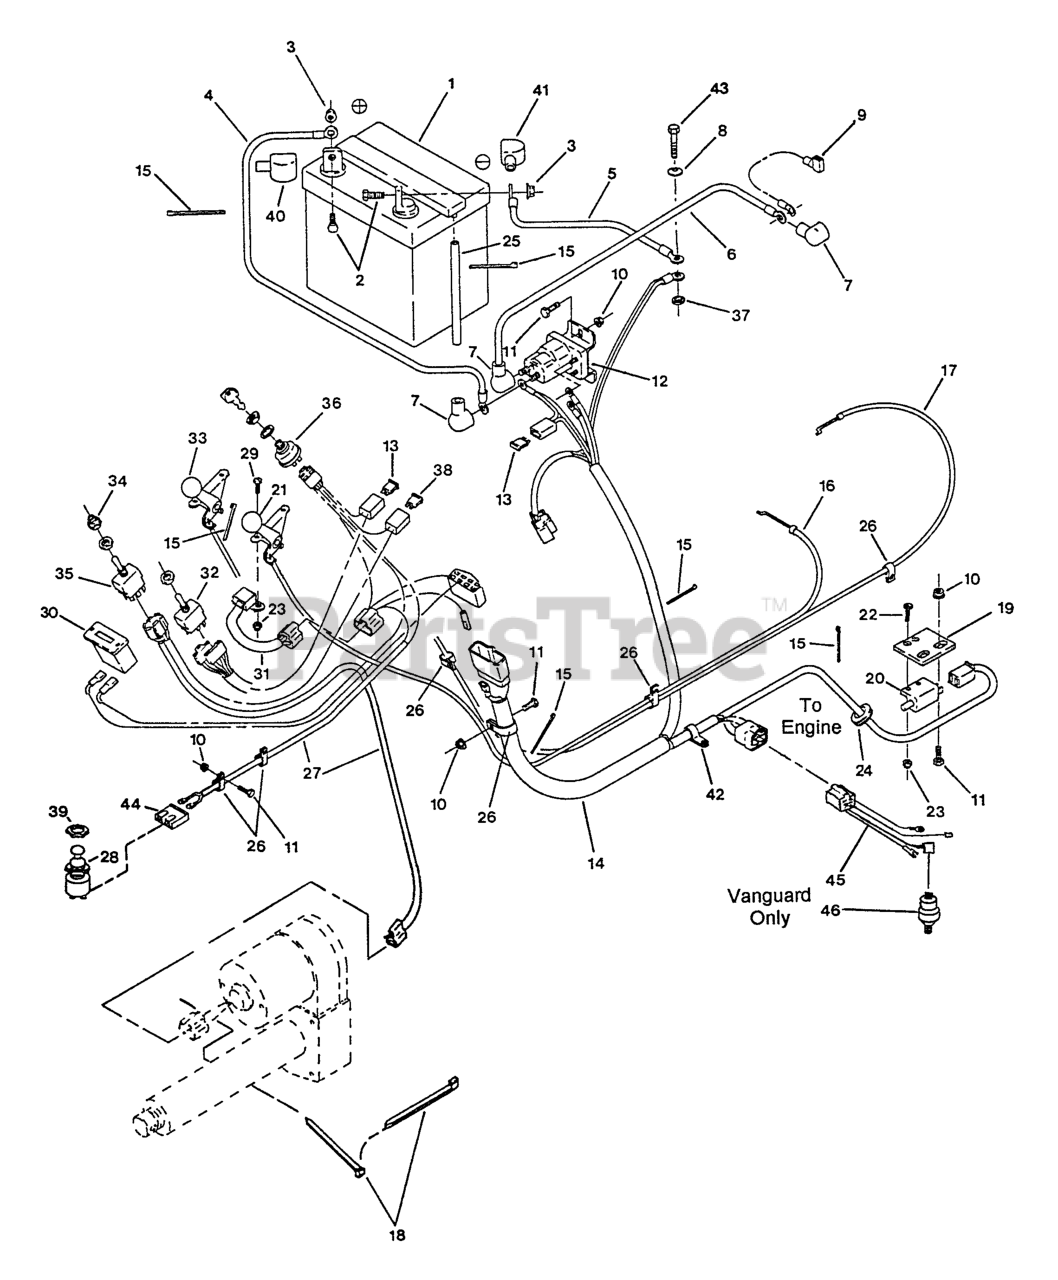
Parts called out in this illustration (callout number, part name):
1	Battery, 12 Volt
5	WIRE-GROUND
6	WIRE,BATTERY POSITIVE
7	INSULATOR-SOLENOID
8	WASHER-SPRING
13	FUSE-BLADE TYPE, 20 AMP
15	TIE-CABLE
18	TIE-PLASTIC
19	BRACKET,SAFETY SWITCH
20	SWITCH-OPEN, NORMALLY
21	KNOB-BALL
24	GROMMET
26	CLIP-LOOM
28	SWITCH,PUSH BUTTON
30	METER-HOUR
31	MODULE,OPC
32	SWITCH,W/TERM CLIPPD
33	KNOB-BALL, BLACK
34	BOOT-SWITCH, TOGGLE
35	SWITCH-TOGGLE, DPDT
36	SWITCH,IGNITION
38	FUSE-BLADE TYPE, 30 AMP
41	INSULATOR, BATTERY -
42	CLIP-LOOM
44	CONNECTOR,PACKARD 2 WAY
45	WIRHRNS,ENG ADAPTER
46	SWITCH-OIL PRESSURE
